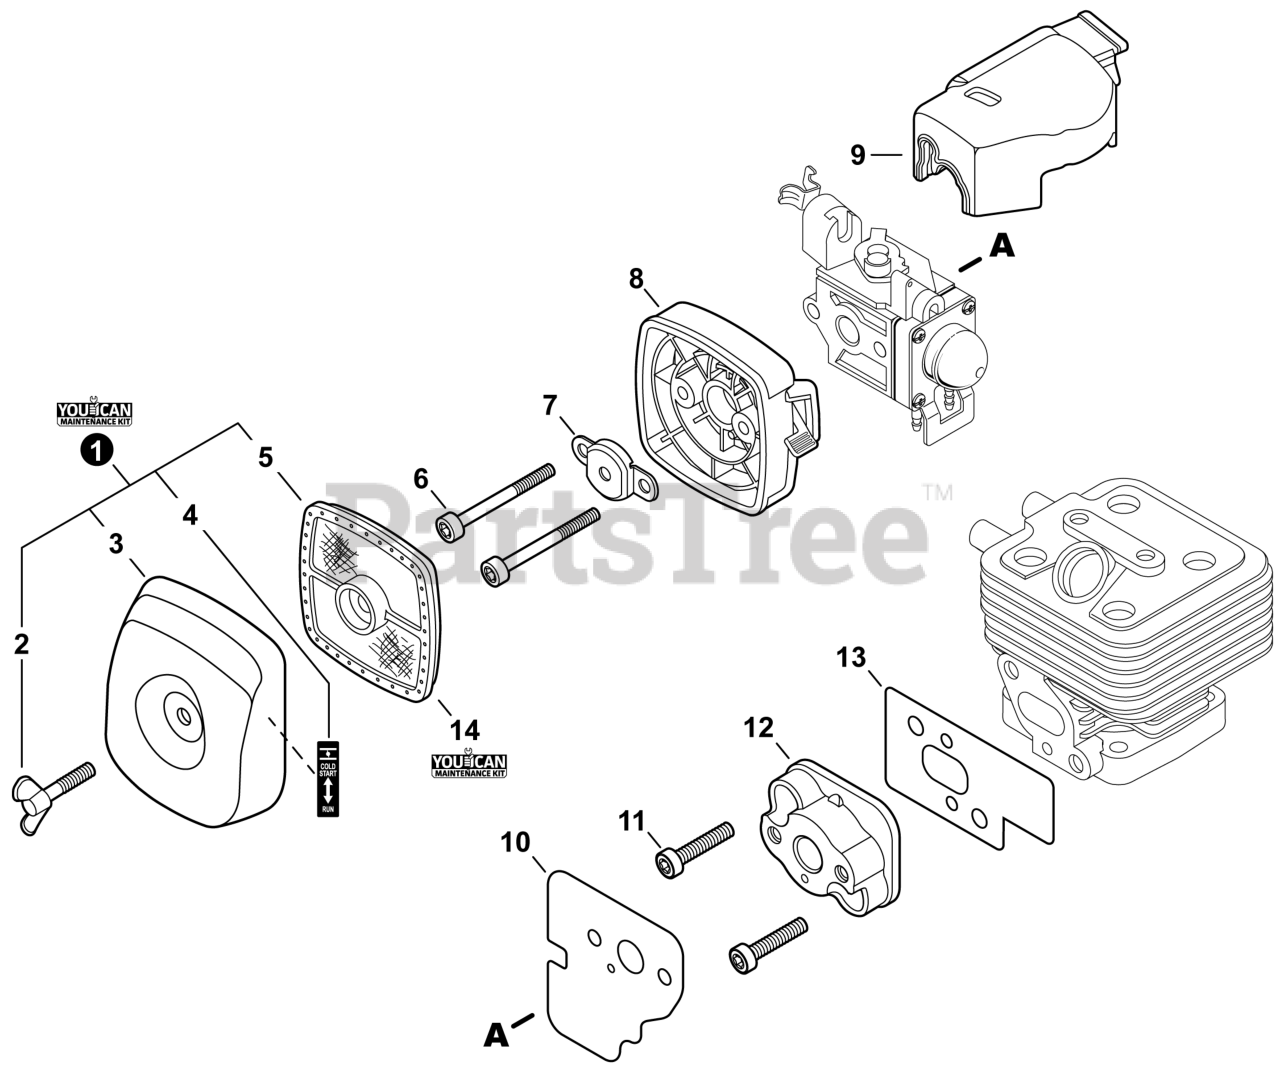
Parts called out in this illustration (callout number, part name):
1	FILTER KIT, AIR - YOUCANT
2	BOLT, WING 5x20
3	COVER, AIR FILTER - BLACK
4	LABEL - CHOKE
5	FILTER, AIR - DOUBLE LAYER
6	BOLT, TORX 5x65
7	PLATE, PREVENT
8	CASE, AIR FILTER
9	COVER, DUST
10	GASKET, INTAKE
11	BOLT, TORX 5x25
12	INSULATOR, INTAKE
13	GASKET, INTAKE
14	TUNE-UP KIT - YOUCANT
